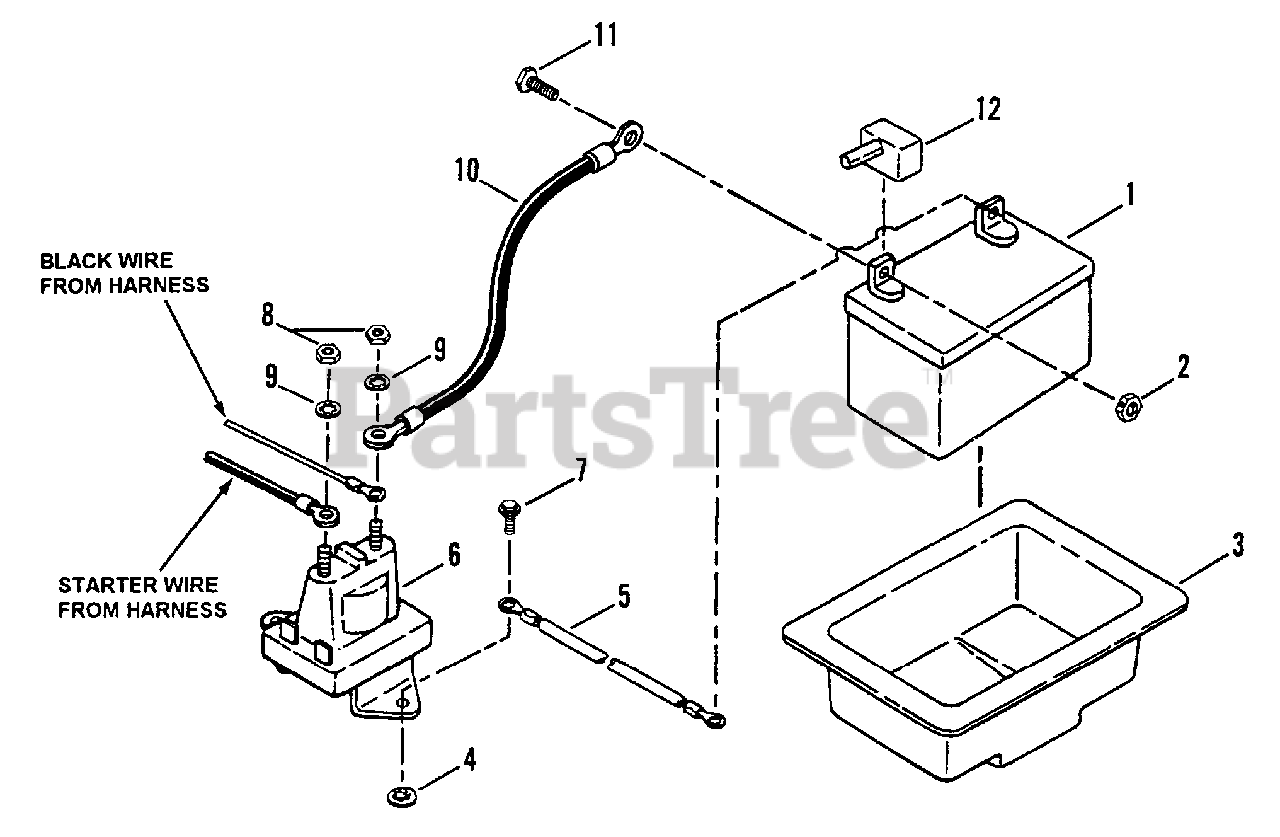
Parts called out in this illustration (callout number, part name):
1	KIT, Battery
2	NUT, 1/4-20 Hex Center Lock
3	TRAY, Battery
4	RETAINER, Screw
5	CABLE, Ground (Black)
6	SOLENOID
7	SCREW, 1/4-20 x 1/2" Self-Tapping
8	NUT, 1/4-20 Hex Jam
9	WASHER, 1/4 Internal Tooth Lock
10	CABLE, Positive (Red)
11	SCREW, 1/4-20 x 5/8" Hex Head Cap
12	COVER, Positive Terminal
